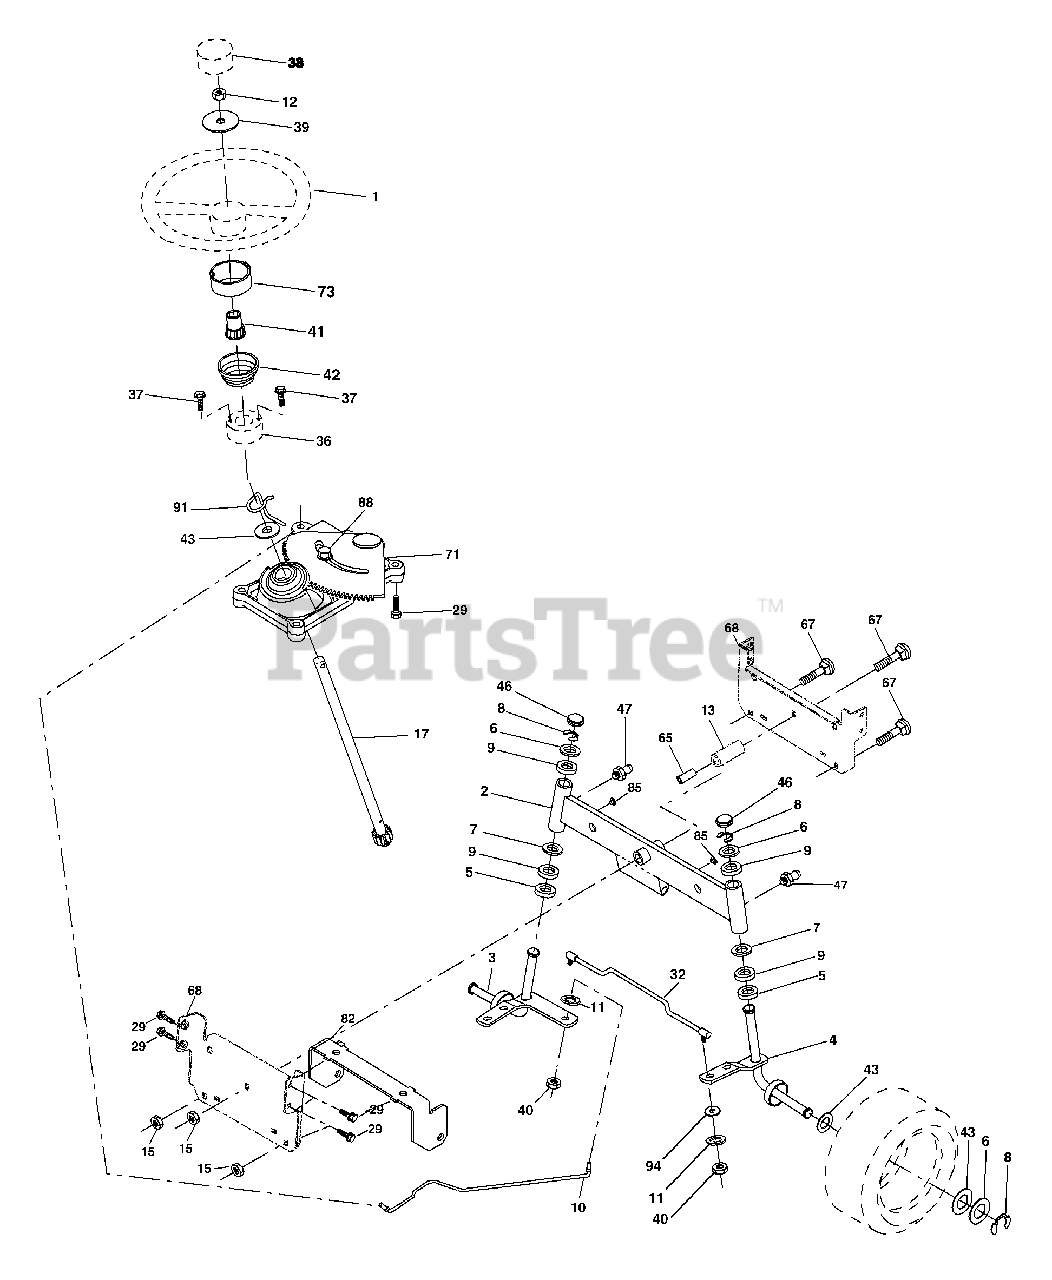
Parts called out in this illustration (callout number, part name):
1	Wheel Steering
2	Axle Welded Asm
3	Spindle Asm LH
4	Spindle Asm RH
5	Bearing Race Thrust Harden
6	Washer 25/32 X 1-5/8 X 16 Ga.
7	Washer 27/32 x 1-1/4 x 16 Ga.
8	Ring Klip #t5304-75
9	Bearing Col. Strg.
10	Link Drag
11	Washer Lock Hvy Hlcl Spr 3/8
12	Nut Hex Jam Toplock 1/2-20 UNF
13	Spacer Brg Axle Front
15	Nut Hex Flange Lock
17	Shaft Asm Strg
29	Screw 3/8-16x3/4
32	Rod Tie
36	Bushing Strg
37	Screw TT #32.5 x 5 x 3/8 Flange
38	Cap Wheel Steer
39	Washer 9/16 x 1-1/2 x 11 Ga.
40	Nut Lock Center 3/8-24 Unf
41	Adaptor Wheel Strg
42	Boot Steering
43	Washer 25/32 X 1 1/4 X 16 Ga.
44	Extension Steering
46	Cap Spindle Fr Top Blk
47	Fitting Grease
65	Spacer Brace Axle
67	Bolt Rdhd Sqn 3/8-16 x 2-1/4
68	Brace, Axle
71	Steering Asm.
73	Extension Steering
82	Bracket Susp Chassis Front
85	Fastner Christmas Tree
88	Bolt Shoulder 7/16-20 Unc
91	Clip
94	Washer 3/8 x 7/8 x 14 Ga.
